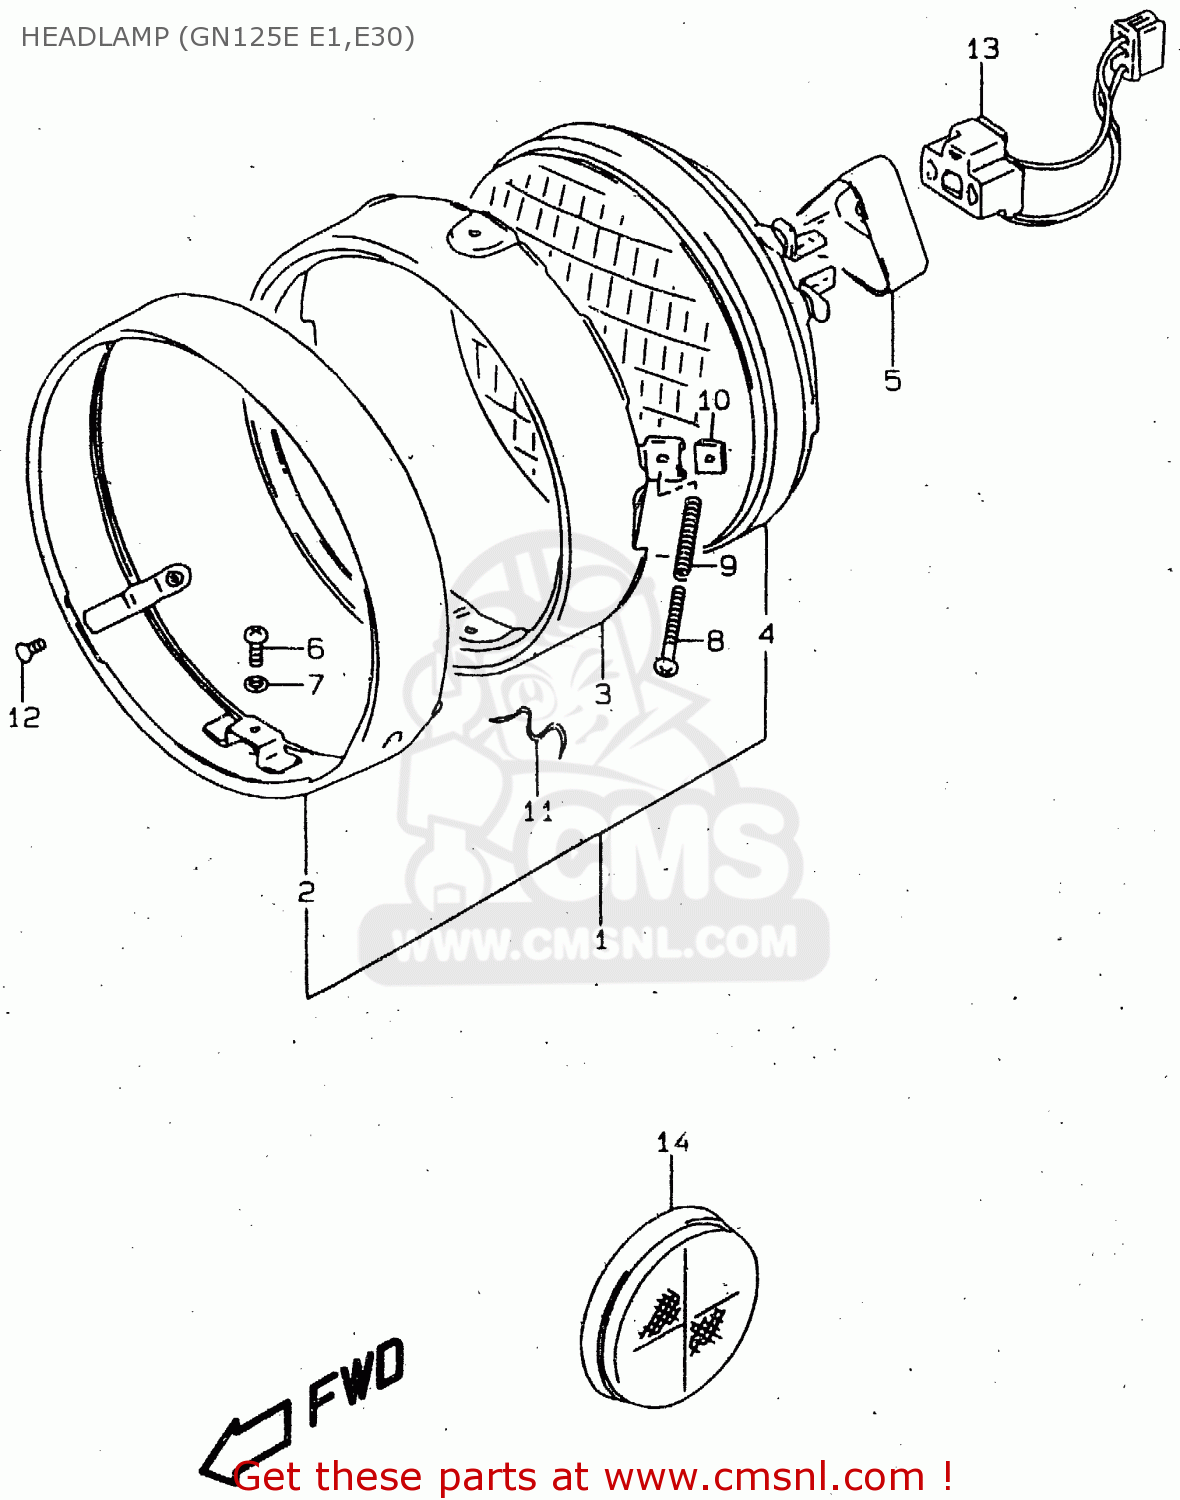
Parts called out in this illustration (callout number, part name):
1	LAMP ASSEMBLY,HEAD
2	RIM
3	RETAINER
4	LAMP UNIT
5	COVER
6	SCREW
7	WASHER,LOCK
8	SCREW
9	SPRING
10	NUT
11	SPRING,HEAD LAMP UNIT
12	SCREW
13	LEAD WIRE,HEADLAMP
14	REFLEX REFLECTOR,RR
